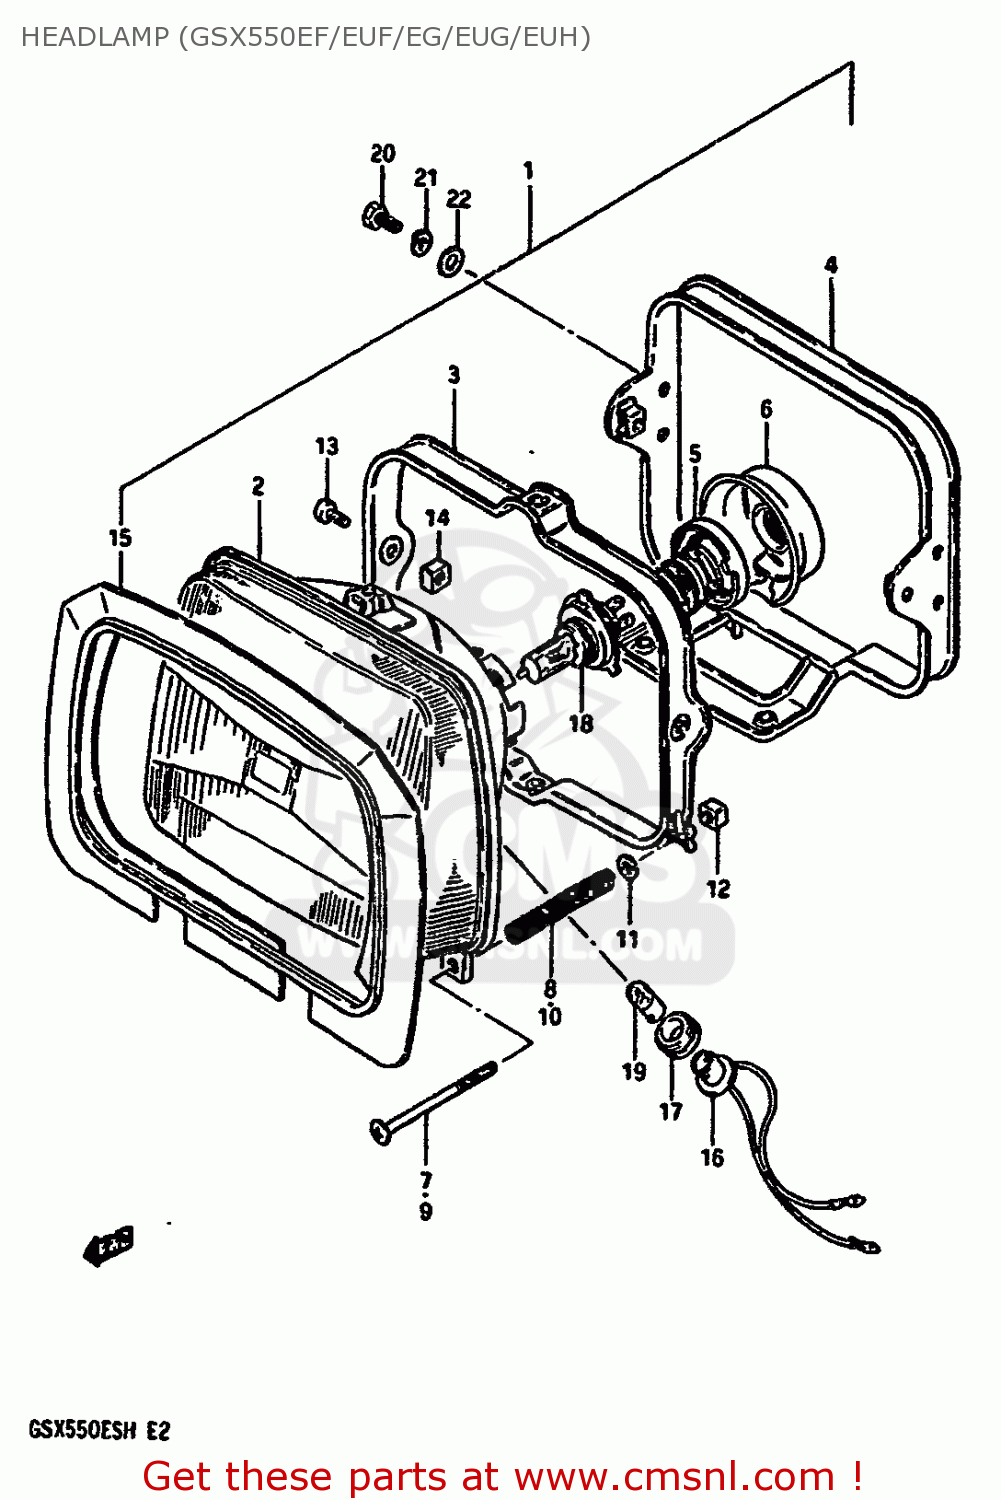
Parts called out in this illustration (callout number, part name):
1	HEADLAMP ASSY
2	UNIT
3	RING,MOUNTING
4	HOUSING
5	HOLDER
6	COVER,HEADLAMP SOCKET
7	SCREW,HEADLAMP ADJUST
8	SPRING
9	SCREW,HEADLAMP ADJUST
10	SPRING,HEADLAMP ADJUST
11	WASHER
12	NUT
13	SCREW
14	NUT
15	SHADE
16	SOCKET
17	JOINT,RUBBER
18	BULB(12V60/55W,H4)
19	BULB(12V4W)
20	BOLT
21	WASHER,LOCK
22	WASHER, LOWER
